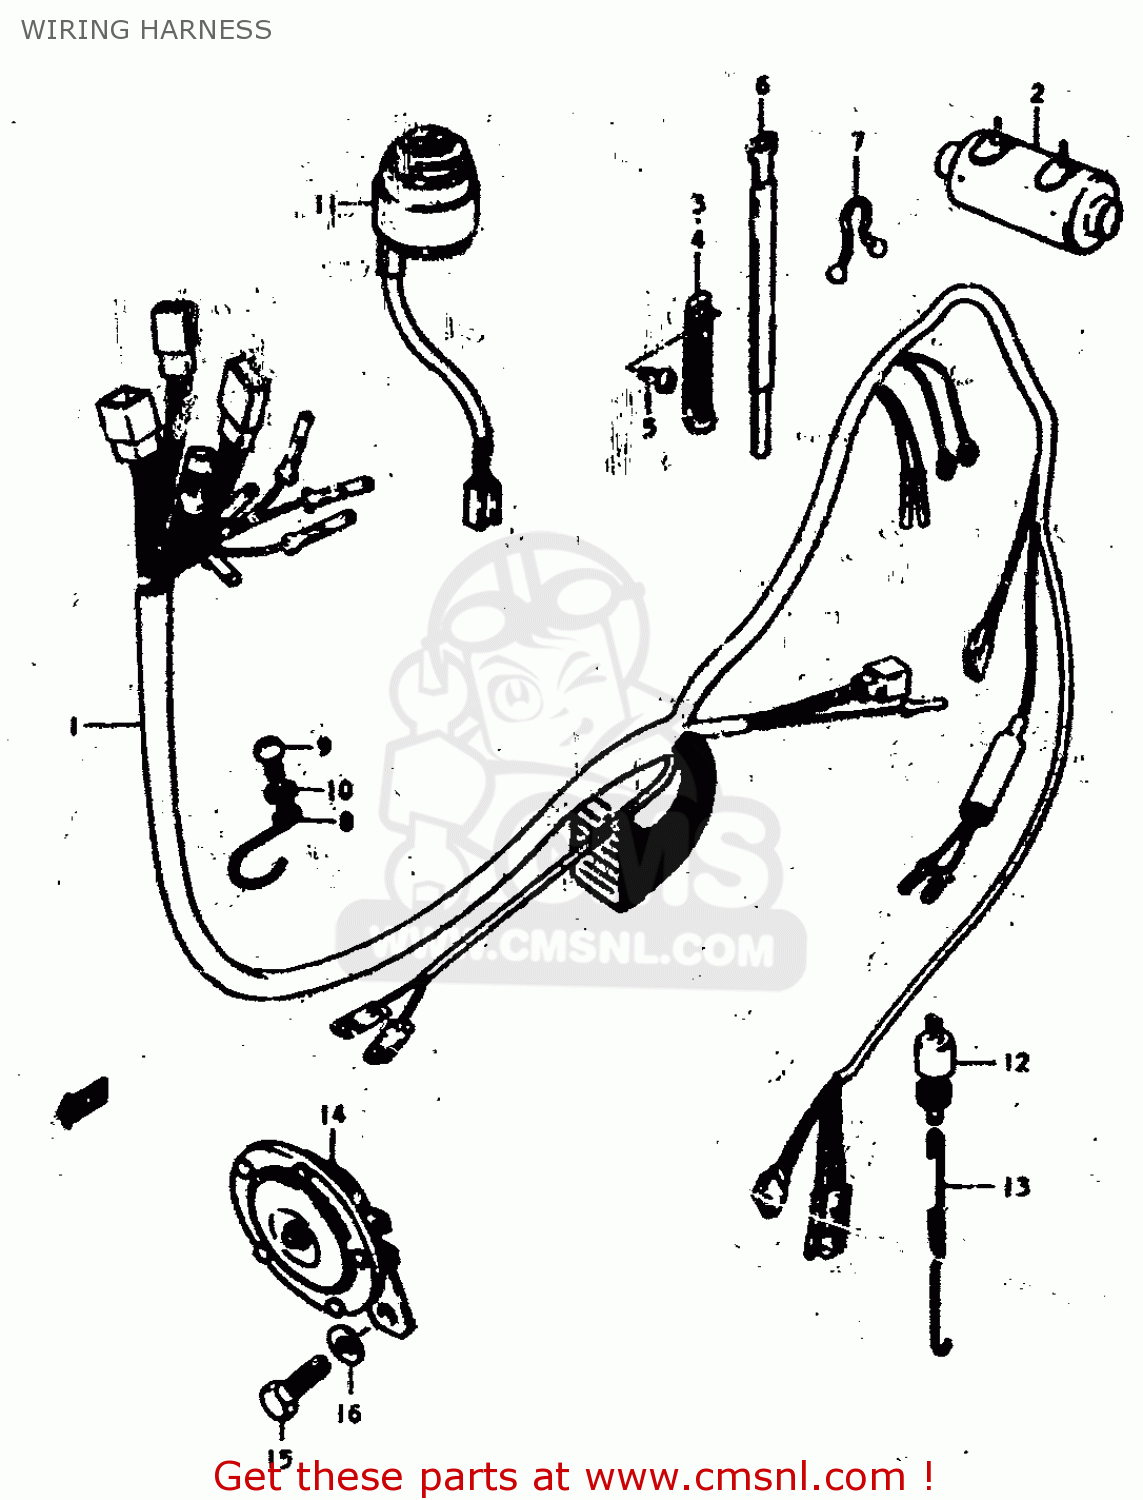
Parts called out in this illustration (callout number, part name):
1	HARNESS,WIRING
2	BOOT,WIRING HARNESS
3	CLAMP
4	CLAMP
5	SCREW
6	CLAMP
7	CLAMP
8	GUIDE,WIRING HARNESS
9	SCREW 6X12
10	WASHER
11	SWITCH ASSEMBLY,IGNITION
12	SWITCH ASSY,BRAKE LAMP
13	SPRING
14	HORN ASSY
15	BOLT 8X12
16	WASHER
